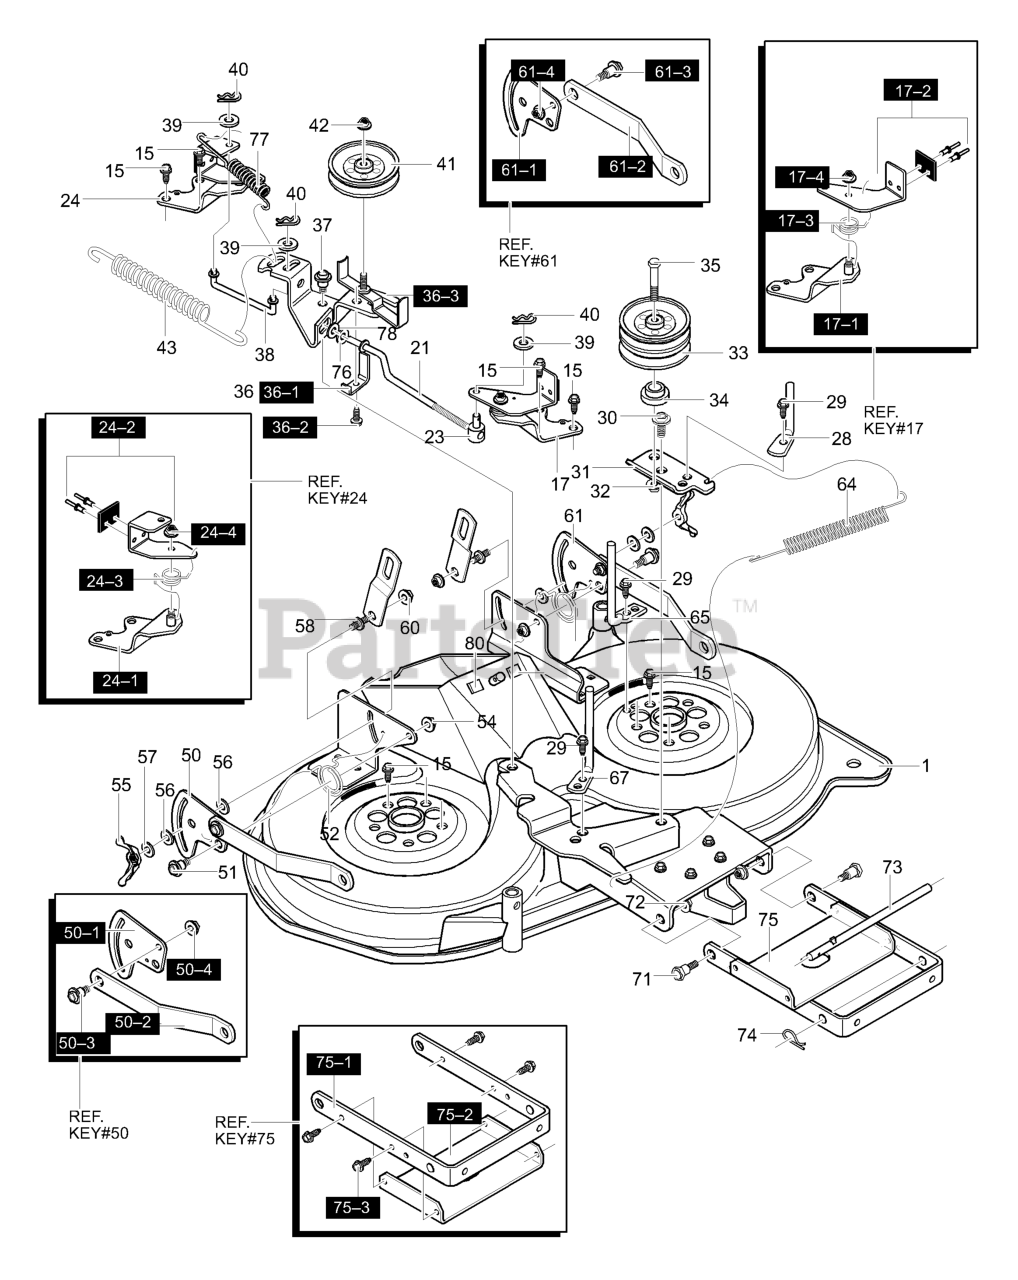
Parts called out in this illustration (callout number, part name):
1	Housing, 40" Deck
17	Brake Arm Assembly LH
17-1	Brake Support Assembly LH
17-2	Brake Arm
17-3	SPRING, Torsion
17-4	NUT, 5/16-18
21	Link, Brake LH
23	NUT, Adjusting
24	Brake Arm Assembly RH
24-1	Brake Support RH
24-2	Brake Arm RH
24-3	SPRING, Torsion
24-4	NUT, 5/16-18
28	BELT Guide
29	SCREW, 5/16-18 x 0.50
30	BOLT, Shoulder
31	Arm, Double Idler
32	NUT, 3/8-16
33	PULLEY, Idler Double Vee
35	SCREW, 3/8-16 x 3.00
36	Idler Arm Assembly
36-1	SPRING - Belt Guide
36-2	SCREW, 1/4-20x.50
36-3	Idler Arm
37	BOLT, Shoulder
38	Link, Brake RH
39	WASHER, Flat
40	HAIR PIN
41	PULLEY, Idler
42	NUT, 3/8-16
43	SPRING, Extension
50	ASSEMBLY, Plate,Rear Sus Bkt RH
50-1	Plate-Suspension
50-2	Suspension Bracket Rear
50-3	BOLT, Shoulder
50-4	NUT, 3/8-16
51	BOLT, Shoulder
52	SPRING, Torsion RH
53	SPRING, Torsion LH
54	NUT, 3/8-16
55	Wingnut, 5/16-18
56	Pad, Friction
58	PIN, Hanger
60	NUT, 3/8-16
61	ASSEMBLY, Plate Rear Sus Brkt., LH
61-1	Plate-Suspension
61-2	Suspension Bracket, Rear
61-3	BOLT, Shoulder
61-4	NUT, 3/8-16
64	SPRING, Extension
65	BELT Guide
67	BELT Guide
71	BOLT, Shoulder
72	NUT, 3/8-16
73	ROD, Hanger
74	HAIR PIN
75	ASSEMBLY, Bracket & Stiffener
75-1	BRACKET, Front Suspension
75-2	Stiffener
75-3	SCREW, 5/16-18 x 0.75
76	FLATWASHER
77	SPRING, Extension
78	WASHER, Flat
80	Pad, Adhesive
